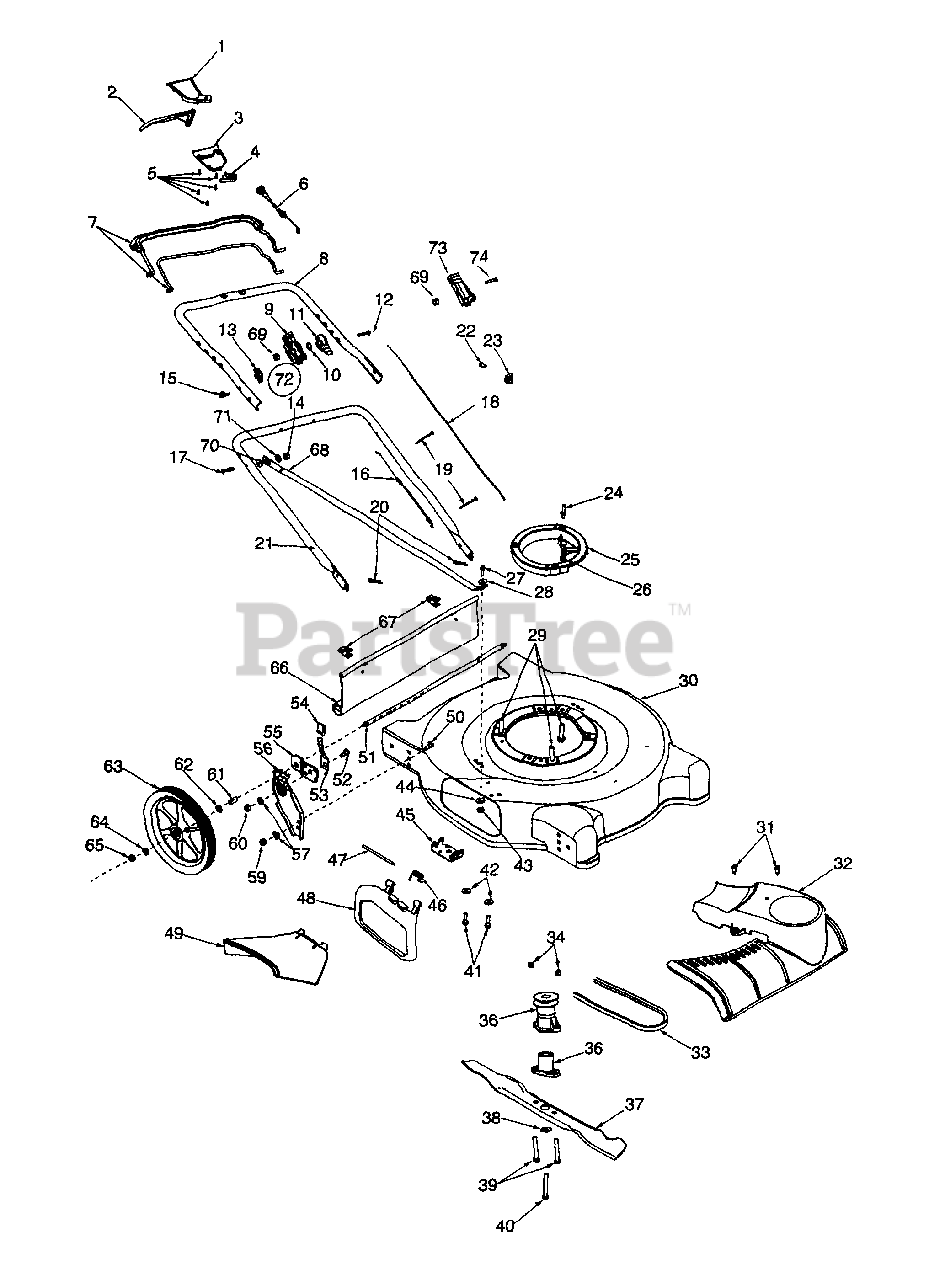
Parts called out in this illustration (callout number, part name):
1	Upper Drive Cover
2	Drive Lever
3	Lower Drive Cover
4	Mounting Cap
5	Screw # 10-16 x .625
6	Drive Cable
9	Throttle Housing
10	Curved Washer .663 x .980 x .014
11	Throttle Lever
12	Screw Oval C-Sunk 1/4-20 x 1.81
14	Hex Nut 5/16-18
15	Eye Bolt 1/4-20
16	Throttle Cable: 51"
17	Carriage Bolt 5/16-18 x 2.0
18	Control Cable: 39"
19	Tie Cable
20	Cotter Pin
22	Hex Screw: T: #10-32 x .625
23	Cable Clamp
24	Pin-Belt Keeper
25	Engine Spacer
26	Hex Nut 1/4-20 Thread
27	Hex Screw 1/4-20 x .620
28	Bell Washer .265 x
29	Tapp Screw w/Hex Lock Wash
30	Deck 22" SD
31	Shoulder Screw TT
32	Trans Cover - Black w/Logo
33	V-Belt
34	Hex Lock Nut 1/4-20 Thd.
36	Blade Adapter Kit
37	Blade 22"
38	Bell Washer,396 I.D. x 1.140 O.D. x
39	Hex Screw 1/4-20 x 1.50
40	Hex Screw 3/8-24 x 2.50
41	Tapp Screw 1/4-20 x .500
42	Bell Wash .265 x .75 x .062
43	Hex Nut 1/4-20
44	Bell Washer .265 x .75 x .062
46	Torsion Spring
47	Hinge Pin
48	Mulch Plug
49	Chute Deflector
50	Bolt 3/8-24 x .80
51	Rear Axle
52	Shldr Screw .500 Dia x .434
53	Lever Spring
54	Knob
55	Small Pivot Bar- LH
56	Hex Nut 3/8-24
59	Bell Washer .39 x 1.13 x .062
60	Hex Nut 3/8-16
61	Spacer
62	Wave Washer .510 ID x .750 OD
63	Wheel Complete 14 x 1.6 Grey Bar
64	Flat Washer .406 x .612 x .051
65	Top Lock Jam Nut 3/8-16
66	Rear Flap
67	Hinge Clip
70	Saddle Washer .20 ID x .83 OD
71	Lock Washer 5/16
72	Throttle Comp.
73	Throttle Hsg. w/o Lever
74	Scr. 1/4-20 x 1.31 Oval C-Sunk
